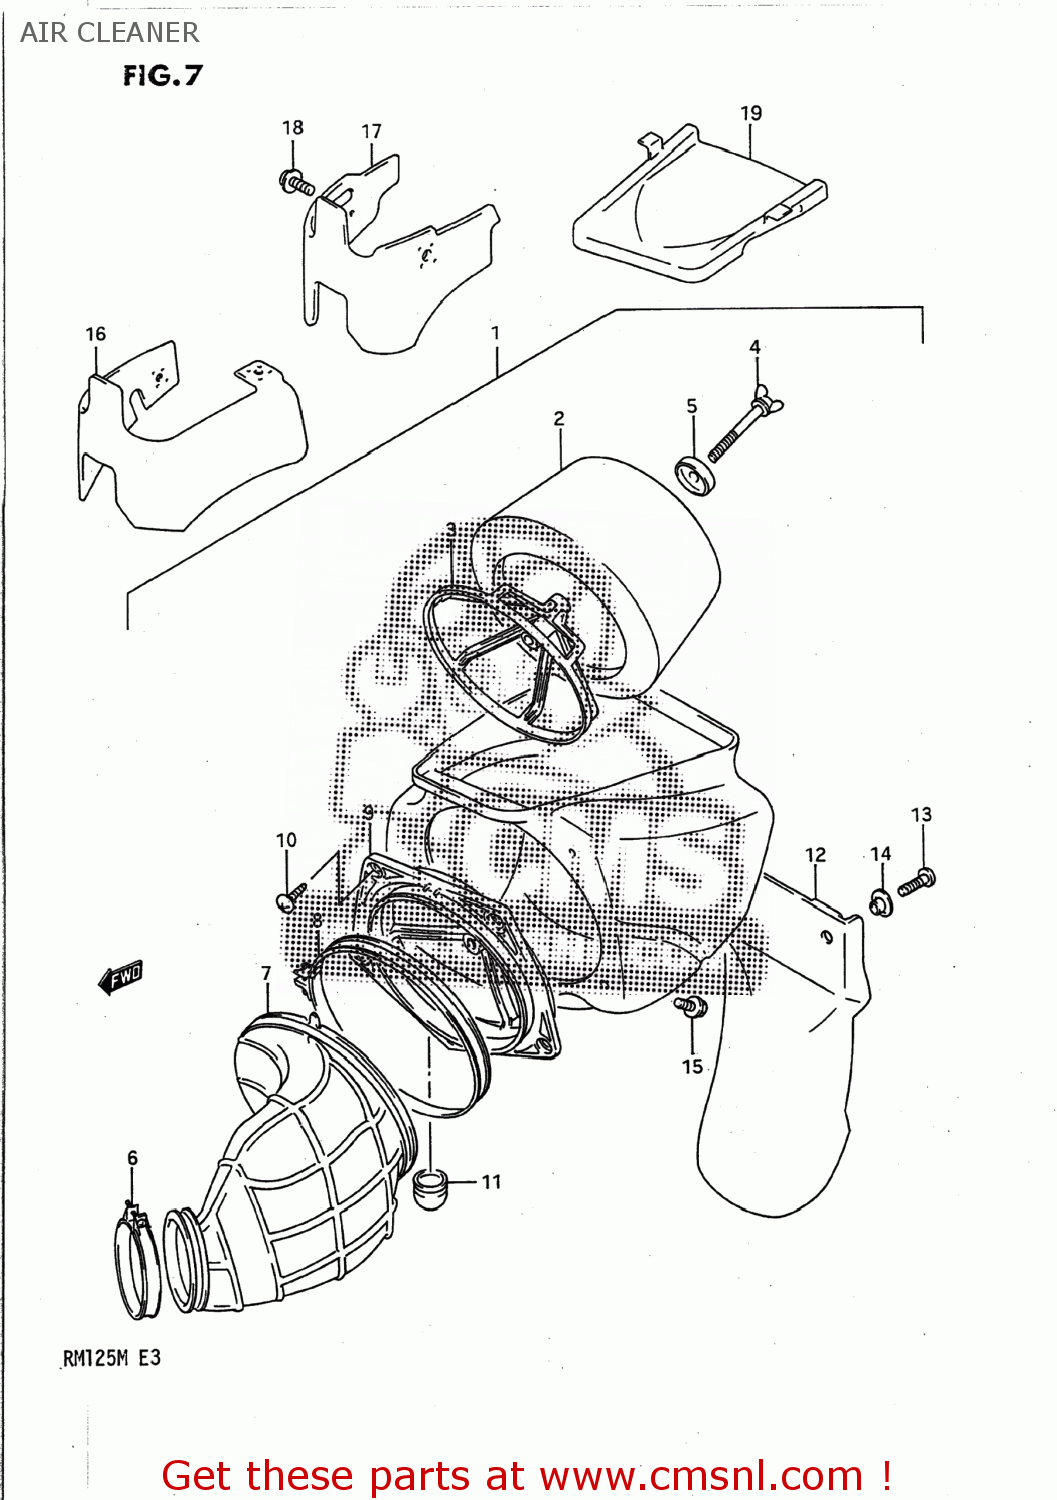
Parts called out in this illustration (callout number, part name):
1	CLEANER ASSEMBLY,AIR
2	FILTER
3	HOLDER,FILTER
4	BOLT,WING
5	WASHER,AIR CLEANER
6	CLAMP
7	TUBE,OUTLET
8	CLAMP
9	HOLDER,FILTER
10	SCREW
11	TUBE,DRAIN
12	GUARD,MUD
13	SCREW
14	COLLAR
15	BOLT
16	GUARD,MUD,C
17	GUARD,MUD
18	SCREW(6X12)
19	CAP,AIR CLEANER
